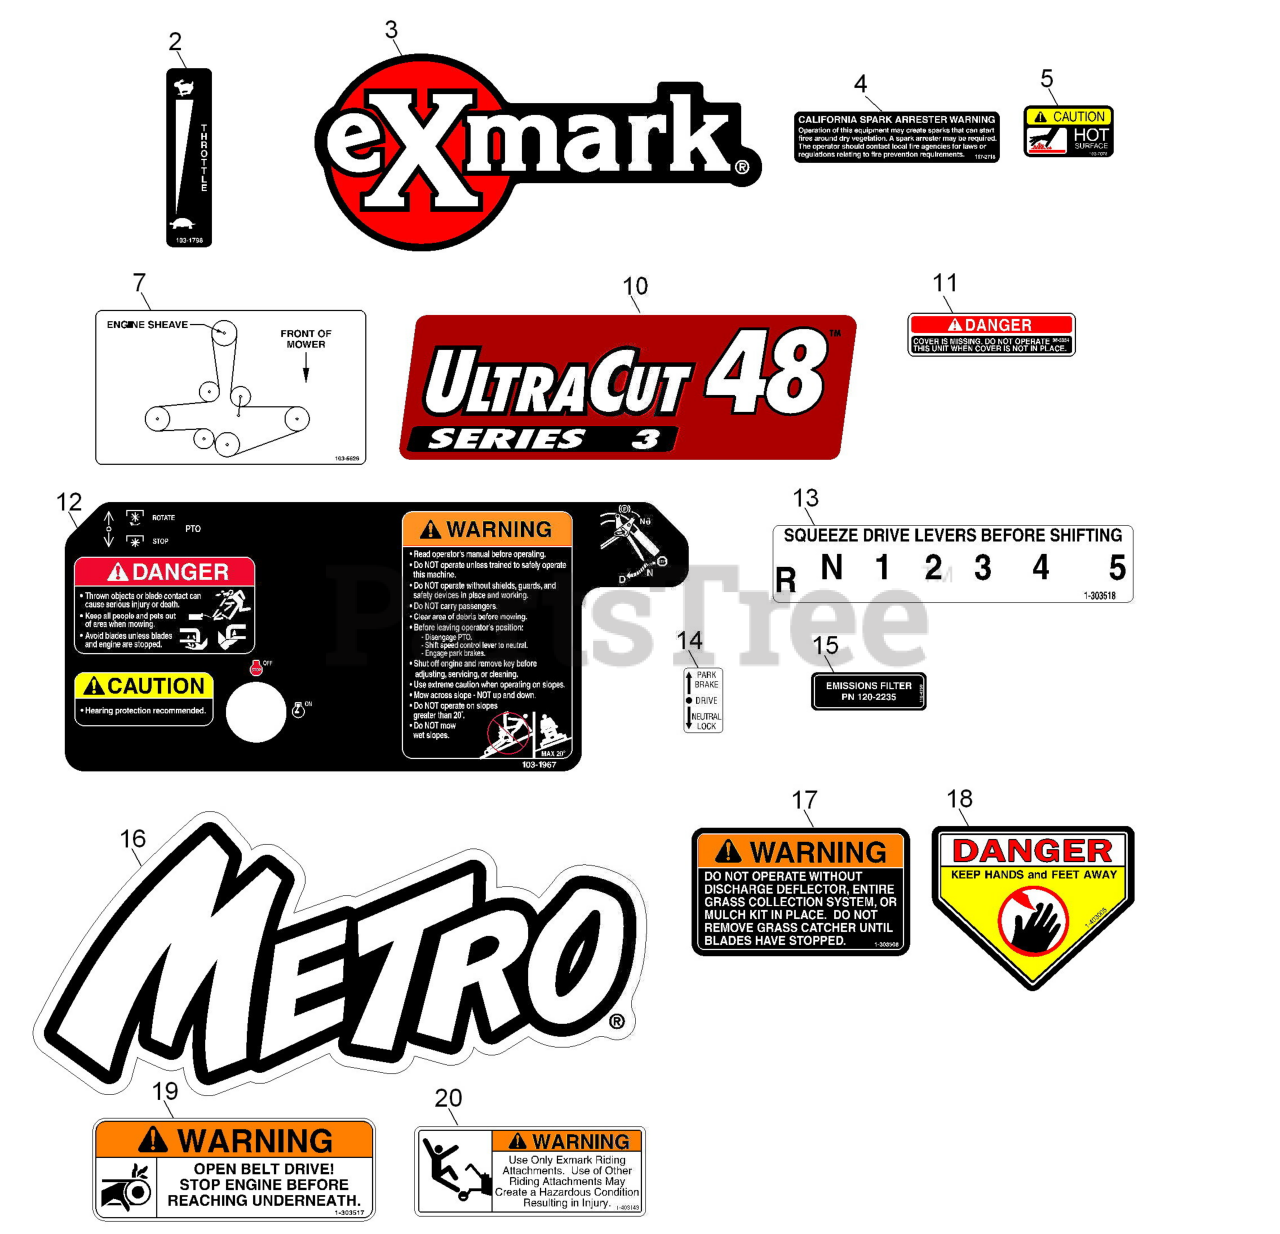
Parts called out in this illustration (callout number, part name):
2	DECAL,THROTTLE ONLY
3	DECAL,EXMARK LOGO
4	DECAL-ARRESTER, SPARK
5	DECAL-CAUTION
7	DECAL,BELT ROUTING
10	DECAL-ULTRACUT 48 SERIES
11	DECAL-COVER, MISSING
12	DECAL,CONSOLE
13	DECAL,SHIFTER
14	DECAL,NEUTRAL/BRAKE
15	DECAL-FILTER, EMISSIONS
16	DECAL,METRO MODEL
17	DECAL-WARNING, DISCHARGE
18	DECAL-DANGER
19	DECAL,BELT DRIVE
20	DECAL,SULKY WARNING
